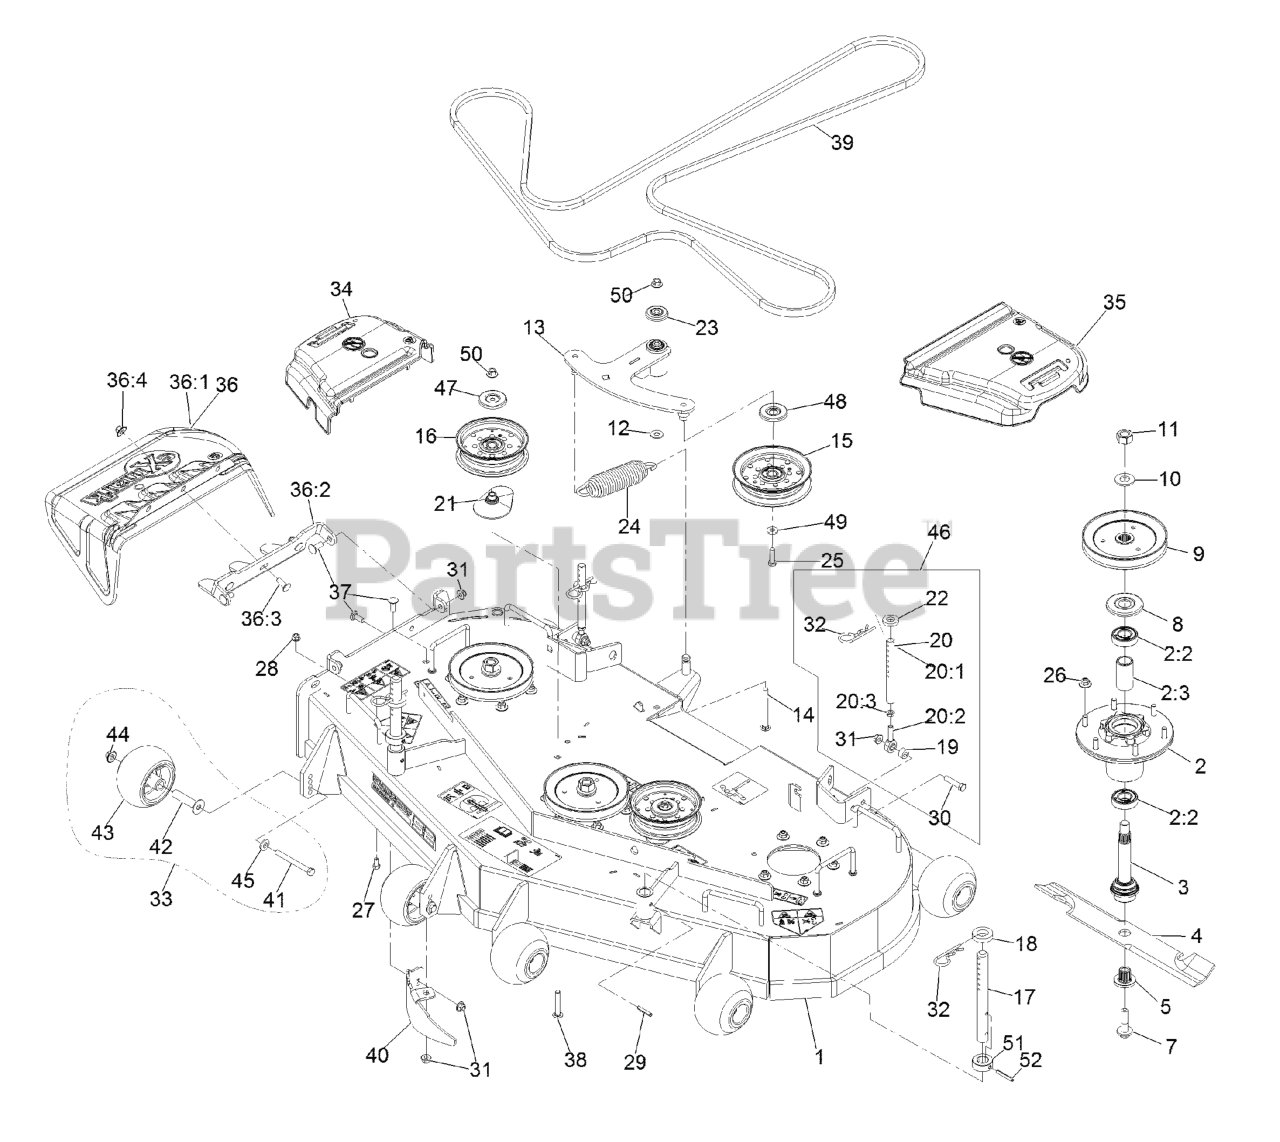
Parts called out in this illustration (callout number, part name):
1	ASM, DECK W/ DECALS, 52"
2	ASM-CUTTER HSG WITH BEARINGS
2:2	BEARING-BALL
2:3	SPACER-BEARING
3	ASM-SPINDLE AND SEAL
5	BUSHING,SPLINED
7	SCREW,SEMS 1/2-20 X 2.19
8	GUARD,BEARING TOP .989
9	SHEAVE,BLADE DRIVE 6.50
11	NUT-HEX
12	WASHER-FLAT
13	ASM, DECK IDLER
14	SCREW-CARR
15	IDLER-PULLEY, FLAT
16	IDLER-PULLEY, FLAT 5.00X1
17	Rod, Deck Support
18	SPACER-DECK SUPPORT
20:1	LINK,SUPPORT
20:2	BALLJOINT
20:3	NUT-HJ
21	SPACER-PULLEY
23	GUARD-TOP
24	SPRING-EXTENSION
25	SCREW-HH
26	Nut-Nyloc 3/8-16 Flg
27	SCREW-HH
28	NUT-HF, NI
30	SCREW-HH
31	NUT-HF, NI
32	PIN,HAIR COTTER
33	KIT, ANTI-SCALP ROLLER
34	COVER-BELT, RH
35	COVER-BELT, LH
36	ASM,DISCHARGE CHUTE
36:1	CHUTE,DISCHARGE
36:2	BRACKET,DISCHARGE CHUTE
36:3	SCREW-CARR
36:4	Nut-Nyloc 3/8-16 Flg
37	SCREW-CARR
38	BOLT-CARR, SHORT NECK
39	BELT, DECK DRIVE
40	BAFFLE-DOGLEG, LZ-VT52
41	SCREW-HH 3/8-16 X 3 3/4 GR 8
42	AXLE, ROLLER
43	ROLLER-SCALP, ANTI
44	Nut-Nyloc 3/8-16 Flg
45	WASHER-BELLEVILLE
46	KIT,SUPPORT LINK W/PIN
47	SHIELD-DUST
48	SHIELD-GUARD, DUST
51	Collar, Deck Height Pin
52	PIN-ROLL
